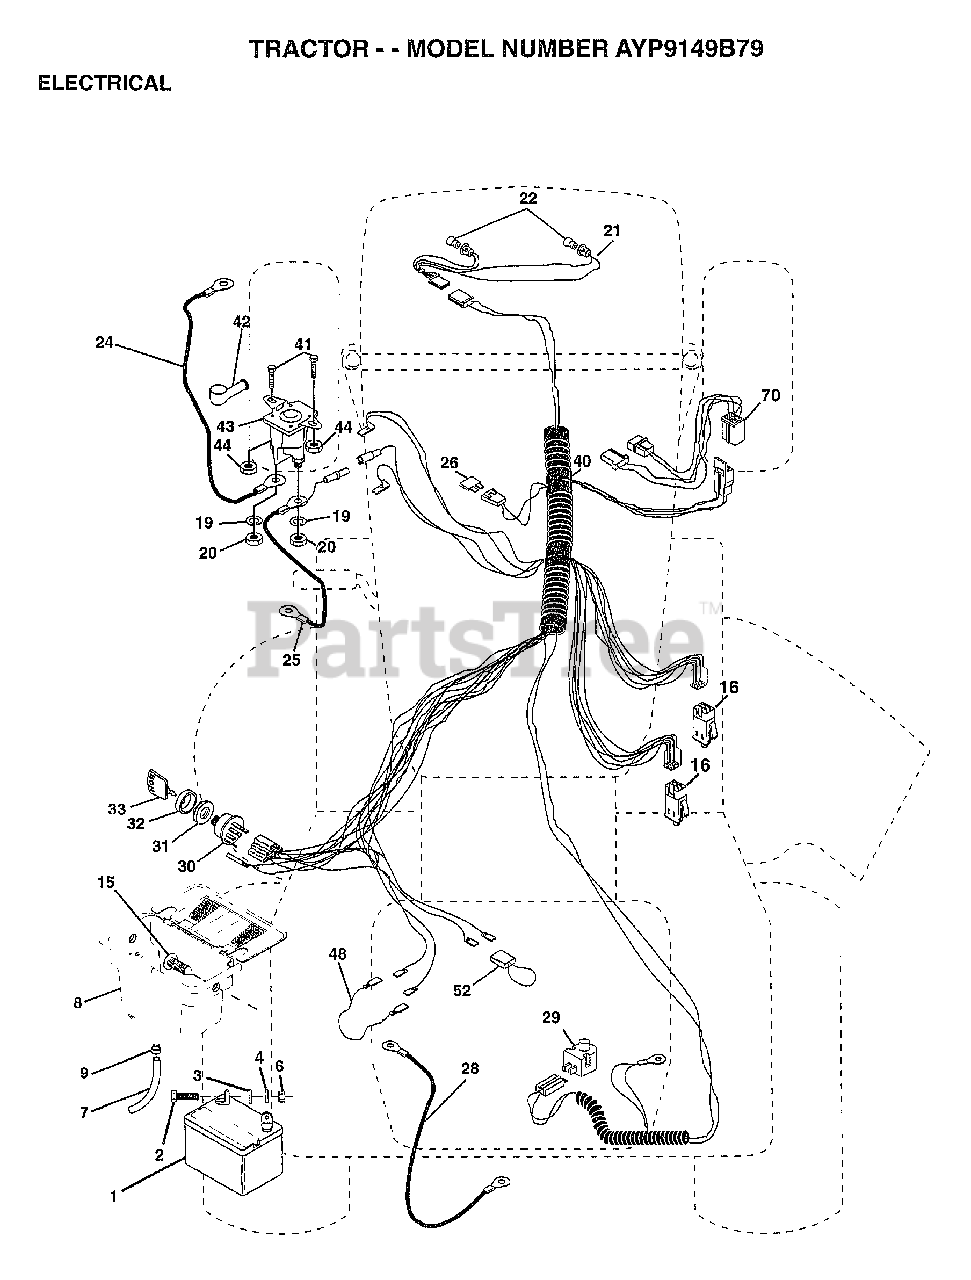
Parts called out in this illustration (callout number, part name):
2	BOLT LT
3	WASHER
4	LOCKWASHER
7	TUBE T
8	"CASE,BATTERY.MECH"
9	HOSE CLAMP T
15	FASTNER.SNAP-IN
16	SWITCH INTERLOCK
20	NUT
21	"HARNESS,LIGHT SOC"
22	HEADLAMP BULB
24	"CABLE T, BATTERY"
25	FUSE HYT
28	CABLE T
29	SWITCH SEAT
30	SWITCH IGN 4POS
31	NUT IGNITION
32	COVER KEY SWITCH
33	KEY
40	HARNESS-IGNITION
41	BOLT HXHD FIN
44	NUT HXKEP 1/4X20
48	ADAPTER AMMETER
52	PROTECTION LOOP
70	HARNESS.ENG.DUAL
